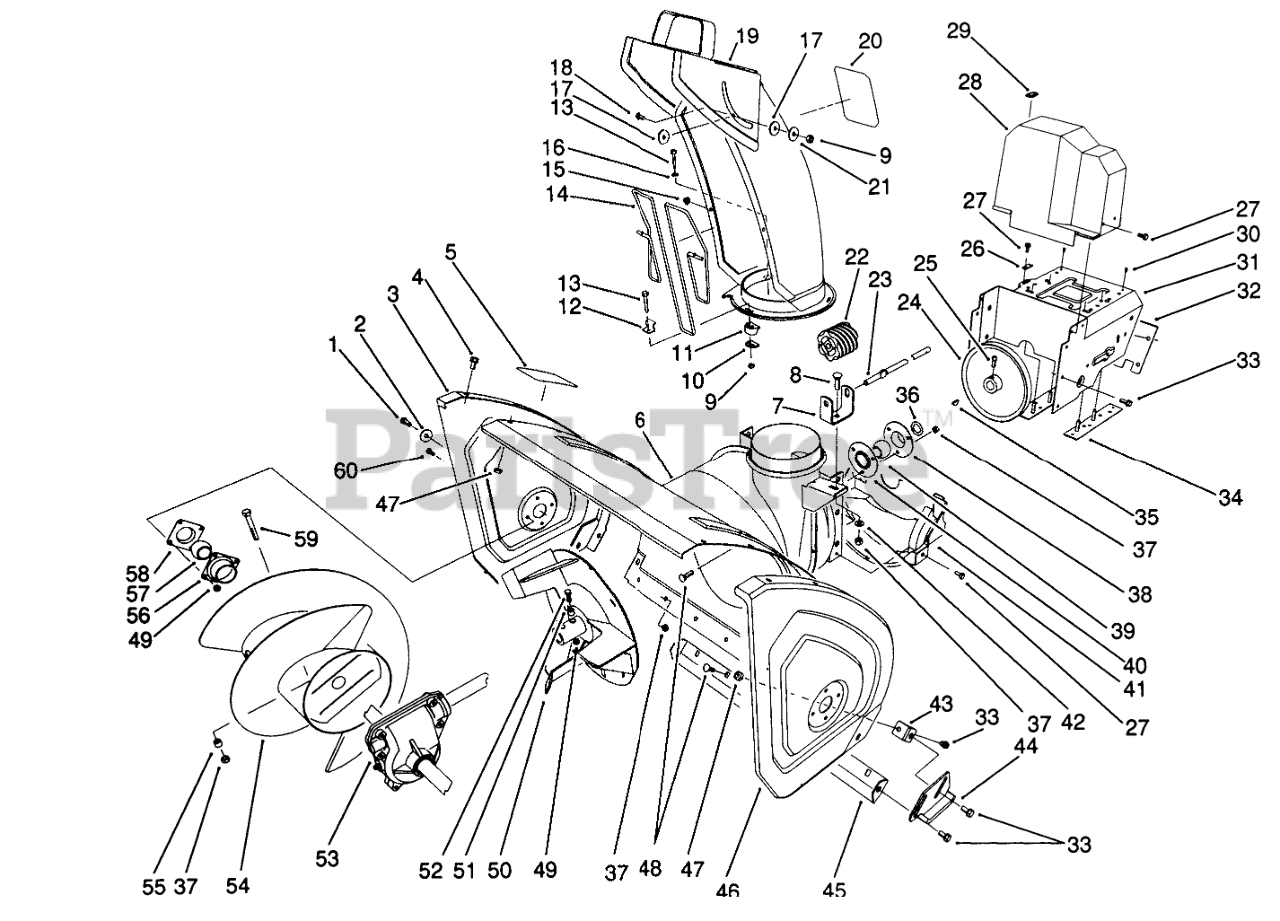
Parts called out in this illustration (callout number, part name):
1	SCREW-HH
2	WASHER
3	PLATE-SIDE, RH
4	SCREW-HHF
5	DECAL-WARNING, AUGER
6	Housing-24"
7	BRACKET-WORM, CHUTE
8	BOLT-CARR
9	NUT-LOCK, NI
10	PLATE-RETAINER, CHUTE
11	RETAINER-CHUTE
12	CLIP-GUARD, CHUTE
13	SCREW-HSH
14	GUARD-CHUTE
15	NUT-PUSH
16	WASHER-FLAT
17	WASHER-PLASTIC
19	Assembly
20	Decal-Danger
21	WASHER-FLAT
22	GEAR-WORM
23	ROD-CHUTE, LOWER
24	PULLEY-IMPELLER
25	SCREW-SET, SQH
26	RETAINER-CABLE
27	SCREW-HWH
28	COVER-BELT, UPPER
29	COVER-CABLE
30	RIVET-POP
31	ENGINE FRAME WA R
32	Cover-Frame, Engine
33	SCREW-HHF
34	PLATE ASM FRM LH 8 B&S
35	KEY-WOODRUFF
36	WASHER-THRUST
37	NUT-LOCK, NI
38	Flange-Bearing (Rear)
39	BEARING-BALL
40	Flange-Bearing (Front)
41	Cover-Belt (Lower)
42	WASHER-PLAIN
43	Bracket-Skid
44	SKID WA
45	Blade-Scraper
46	Plate-Side LH
47	NUT-LOCK, NI
48	SCREW-CARR
49	NUT-LOCK, NI
50	Impeller
51	SPACER
52	SCREW-HHF
53	Auger Gearbox Assembly
54	R/H 28"AUGER WA B
55	SPACER-HUB, AUGER
56	BEARING-FLANGE, FRONT
57	BEARING
58	BEARING-FLANGE, REAR
59	Auger Bolt
60	SCREW-HH
